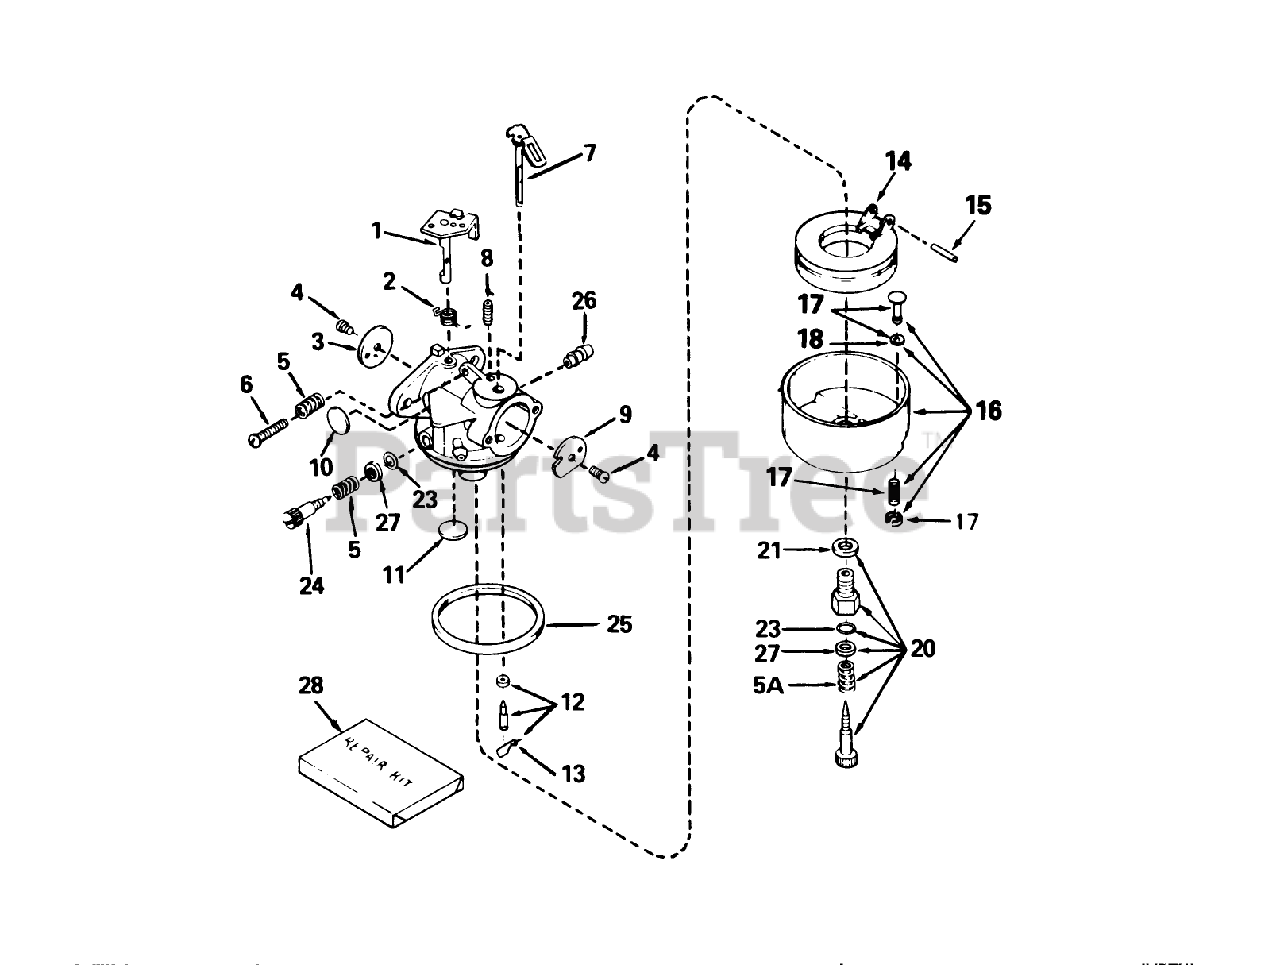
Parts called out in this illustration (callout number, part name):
1	Throttle Shaft and Lever ASM
2	Spring-Return, Throttle
3	Shutter-Throttle
4	Screw-Shutter
5	Spring-Tension
5A	Spring
6	Screw-Throttle Crack Screw / Idle Speed
7	Choke Shaft and Lever ASM
8	Spring-Positioning, Choke
9	Shutter-Choke
10	Plug-Welch, Idle Mixture Well
11	Plug-Welch, Atmospheric Vent
12	Inlet Needle, Seat Clip Assy. (Incl. No. 13)
13	Clip-Spring
14	Float
15	Shaft-Float
16	Float Bowl Asm. (Incl. Ref. # 32, 33)
17	Bowl Drain ASM
18	Gasket-Plunger, Drain
20	Adjustment Screw Assy.,Main (Incl. Ref. #5A,21,23 30)
21	Washer-Bowl Nut
23	ORing
24	Screw-Idle Mix
25	O Ring-Bowl, Float
26	Fitting-Fuel
27	Washer
28	Kit-Repair
